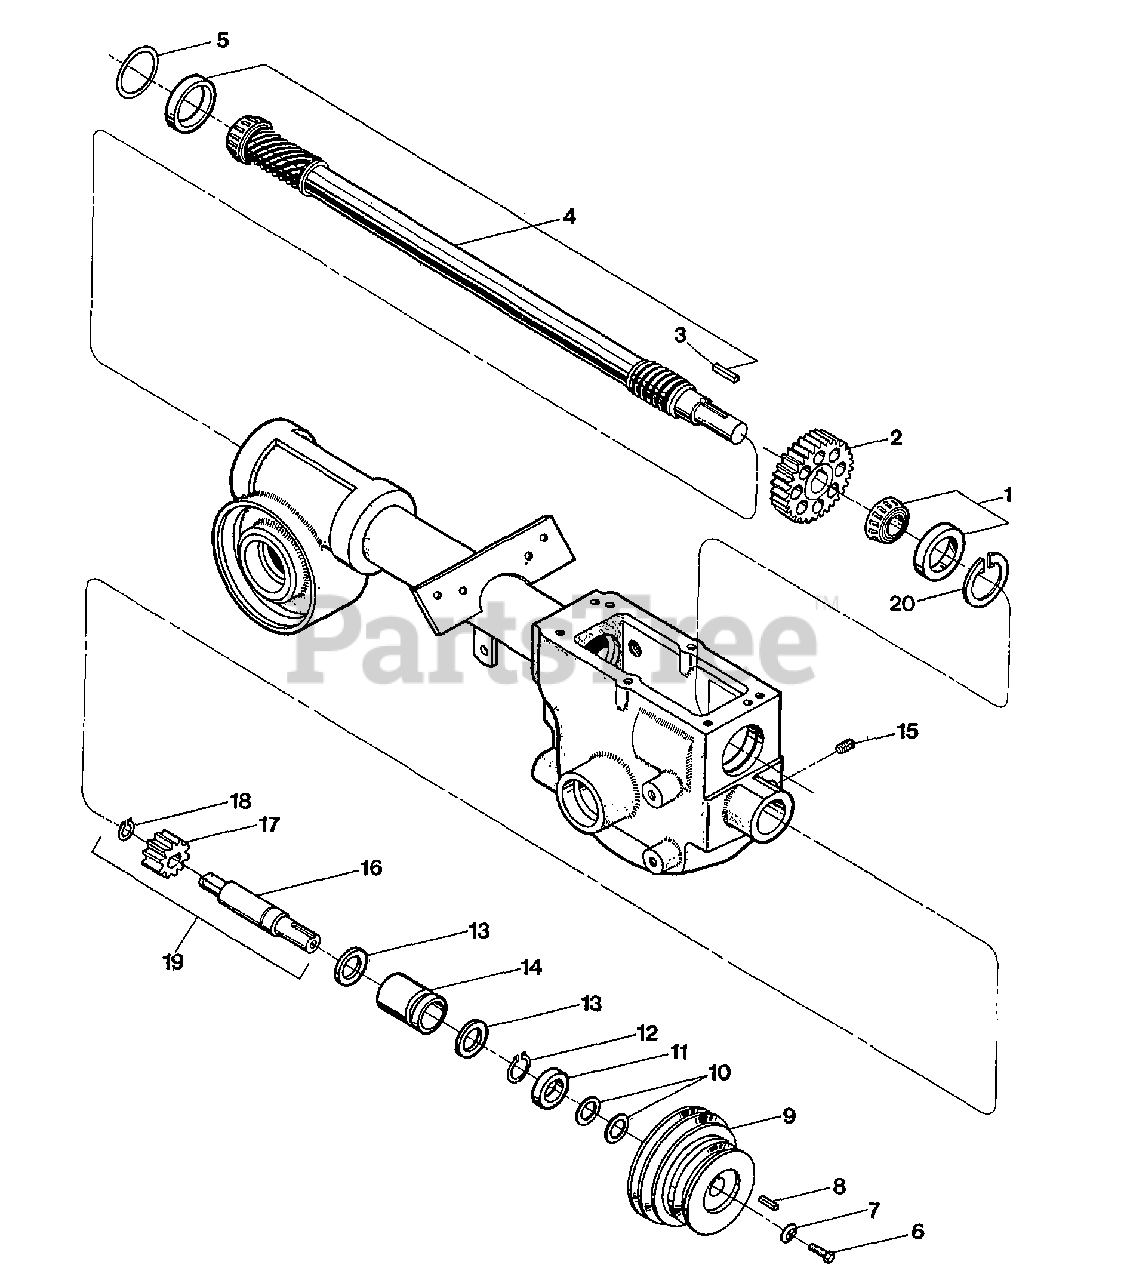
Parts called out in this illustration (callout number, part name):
1	KIT-BRG CONE&RACE-DRIVESHAFT (FRONT OF DRIVE SHAFT)
2	GEAR-SPUR 30 TEETH
3	KEY-.188 SQX1.0
4	KIT-DRIVESHAFT SMFR
4	KIT-DRIVESHAFT
5	SHIM-1.75X1.5X.01
5	SHIM-1.75X1.5X.03
5	SHIM-1.75X1.5X.005
6	SCR-HH 5/16-24X.75 G5 ZP
7	WASHER-.827X.331X.098
8	KEY-.188 SQX1.0
9	PULLEY-TRANS MACH, 3 GROOVES (TWO FOR FORWARD SPEEDS; ONE FOR REVERSE SPEEDS)
10	WASHER # .875 X .65 X .06
11	SEAL-PINION SHAFT PT/85030/00
12	RING-RETAIN EXT .707 ID (SNAP-IN)
13	WASHER-1.022X.752X .059
14	BUSHING-1.24X.75X1.8 GRVD
15	SCR-SS 5/16-18X.375
16	SHAFT-PINION(P-V)
17	GEAR-PINION P/M
18	RING-BOWED EXT .461 ID
19	PINION W/GEAR&SNAP RING (INCL. ONE EACH OF 16-18)
20	RING-RETAINING 5000-181
